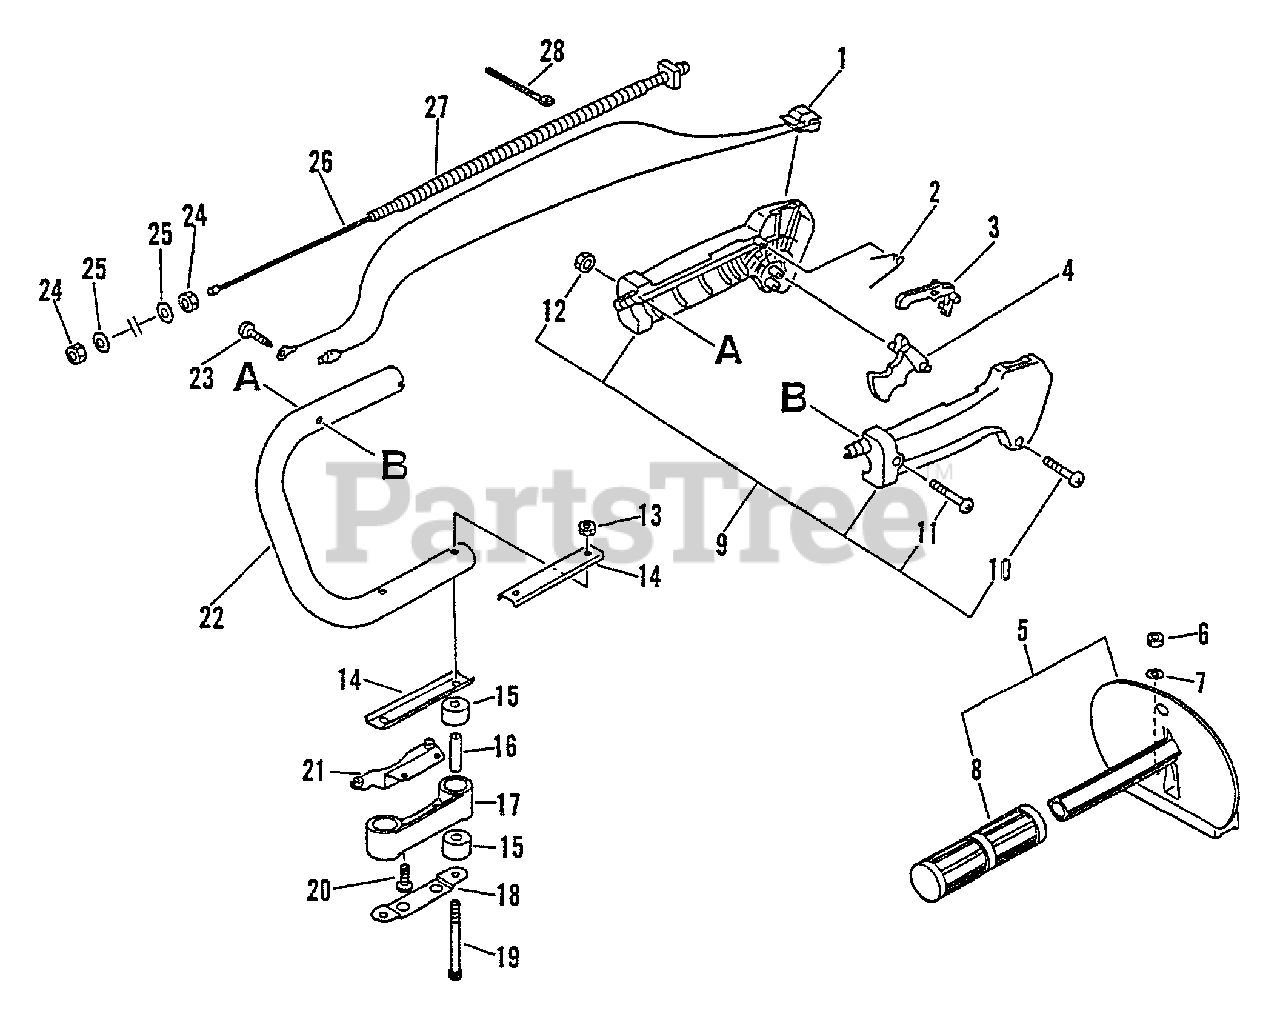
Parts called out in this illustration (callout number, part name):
1	IGNITION SWITCH ASSY
2	SPRING, TORSION
3	LOCKOUT, TRIGGER
4	TRIGGER, THROTTLE
5	BRACKET ASSY
6	NUT, LOCK 6
7	WASHER 6.5×13×1
9	CONTROL HANDLE KIT
10	SCREW 3×25
11	SCREW 5×30
12	NUT M5
13	NUT, LOCK M5
16	SPACER
17	BRACKET, HANDLE
19	BOLT 5×60
20	SCREW 5×16
22	HANDLE, REAR
23	SCREW 5×10
25	WASHER 6.5×11.5×0.8
26	CABLE, THROTTLE
28	TIE, CABLE
